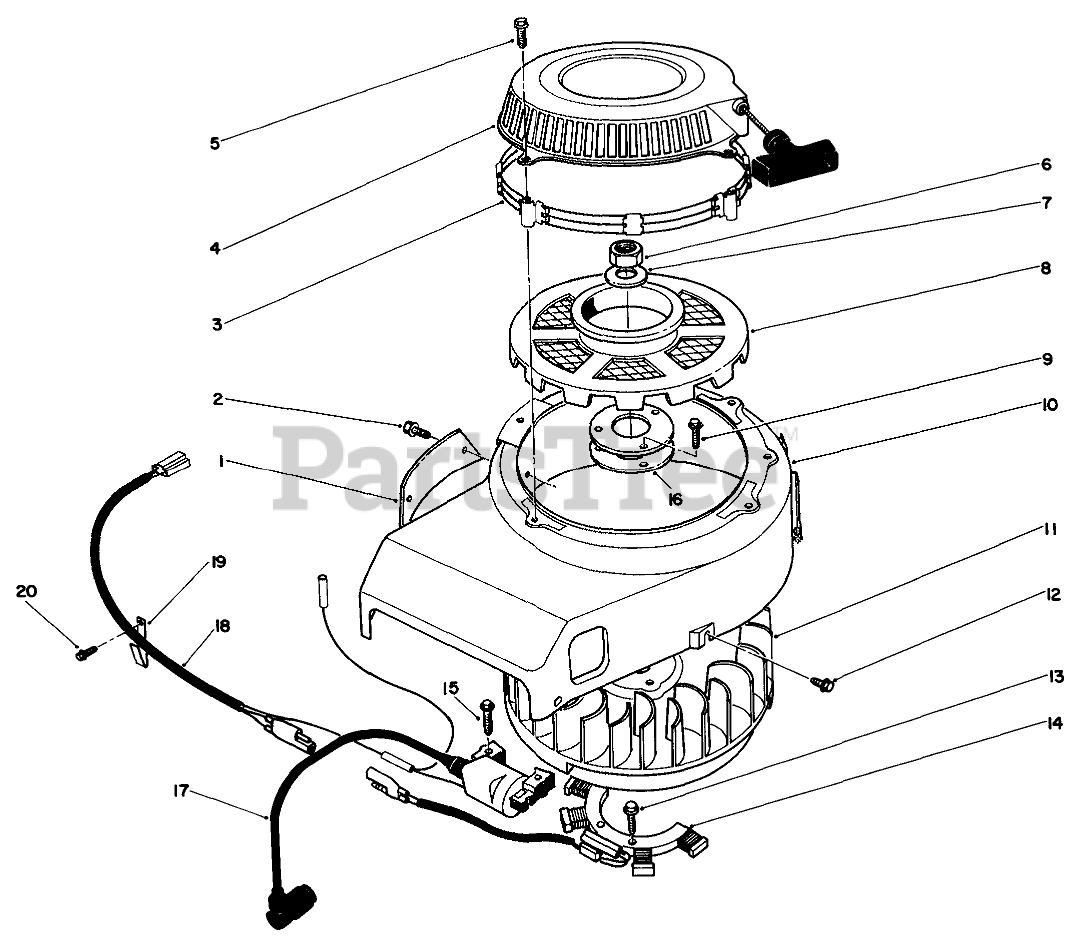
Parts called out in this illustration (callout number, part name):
2	Screw
4	Recoil Starter ASM
5	Bolt-Flanged (6X35)
9	Bolt-Flanged (8X12)
10	Housing-Fan
11	Flywheel
12	BOLT-FLANGED (6X10)
13	Screw
14	Coil-Charging
15	Bolt
17	Coil
18	Wire Harness
19	Clamp
20	Screw
